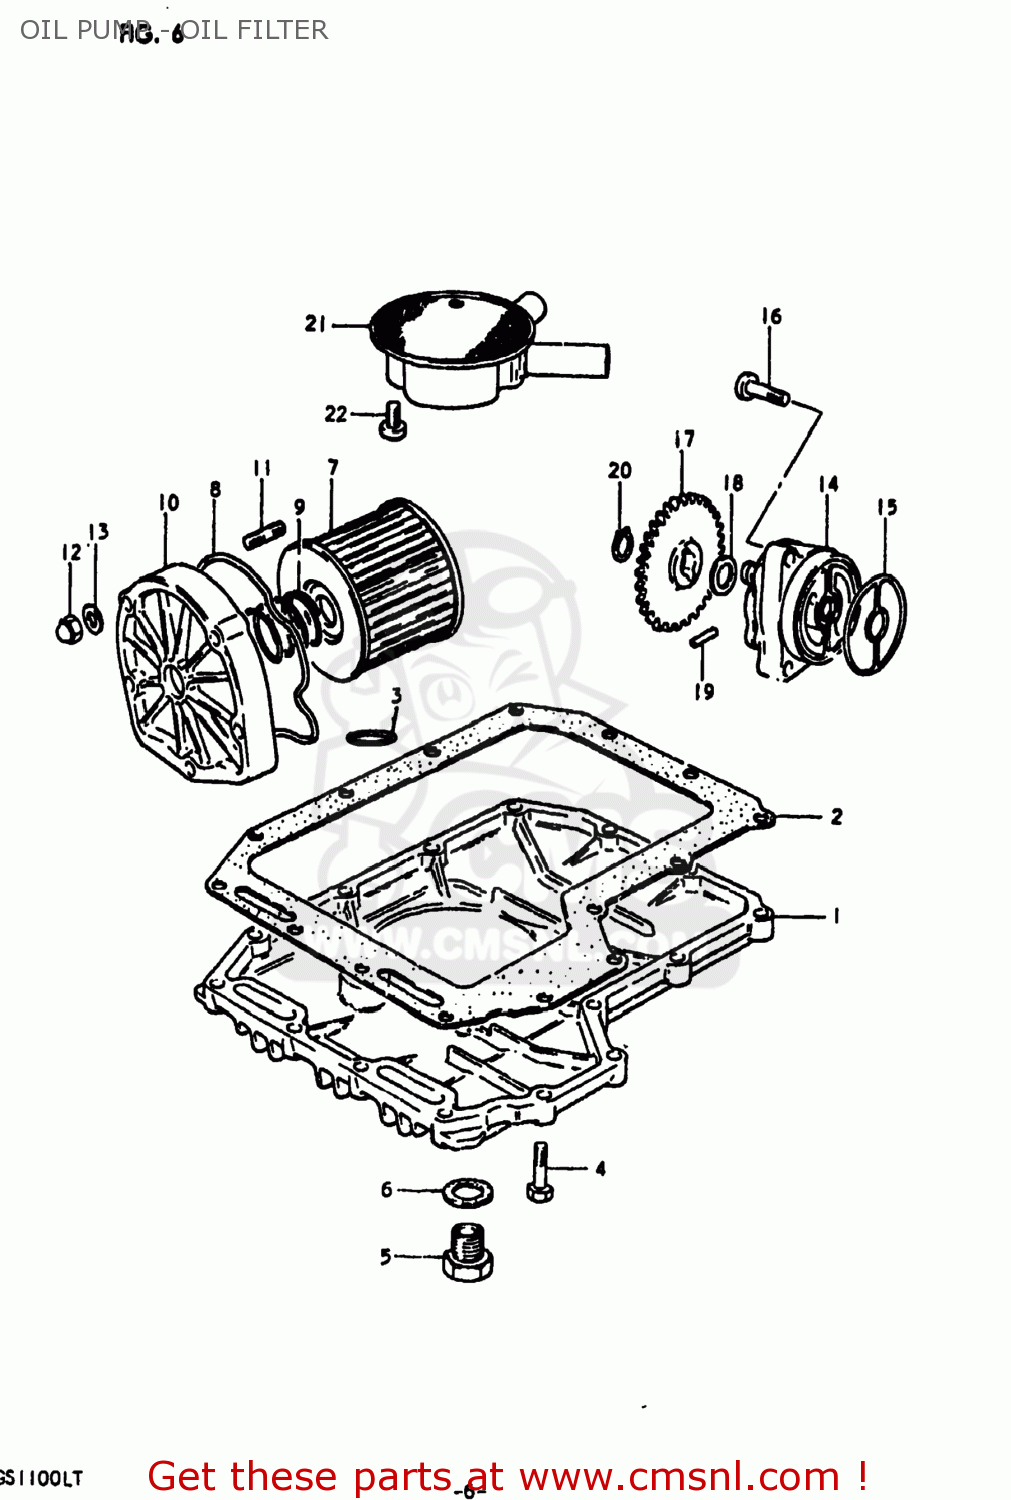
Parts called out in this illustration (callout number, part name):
1	PAN,OIL
2	GASKET,OIL PAN (MCA)
3	O RING(D:3.2,ID:12.9)
4	BOLT
5	PLUG
6	GASKET(14X19.2X2) (NAS)
7	FILTER ASSY,ENGINE OIL
8	O RING,OIL FILTER CHAMBER CAP
9	SPRING
10	CAP,ENG OIL FLTR OUTER CHAMBER
11	STUD 6X25
12	NUT
13	WASHER
14	PUMP ASSEMBLY,OIL
15	O-RING,OIL PUMP
16	SCREW
17	GEAR,OIL PUMP DRIVEN
18	SHIM
19	PIN(4X15.8)
20	CIRCLIP
21	STRAINER,ENGINE OIL
22	SCREW 6X12
